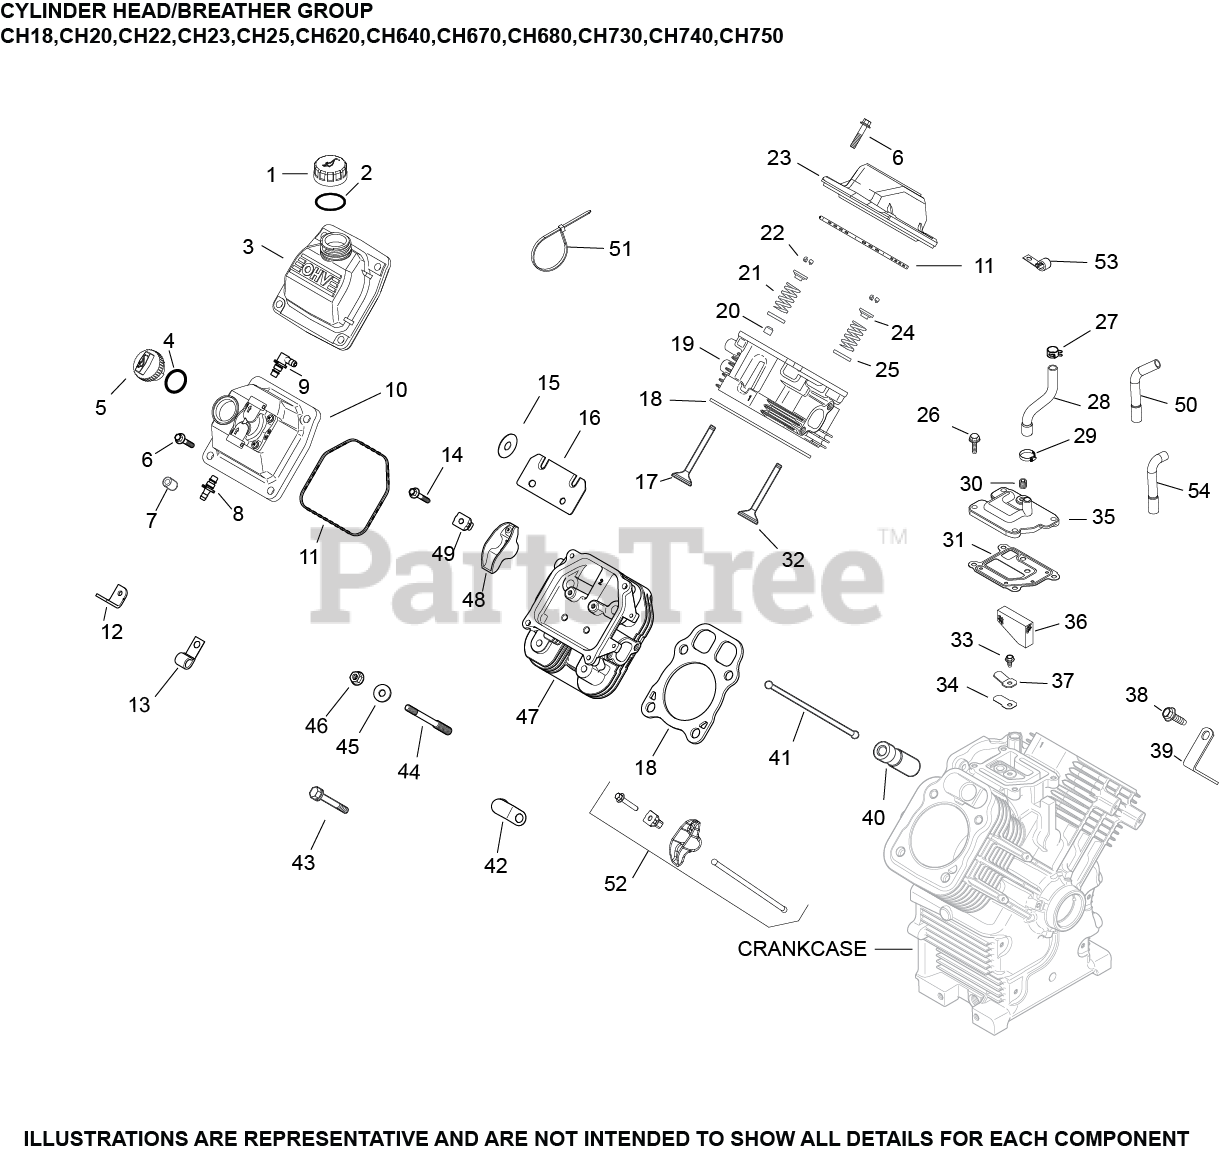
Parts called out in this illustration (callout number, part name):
1	KIT, OIL FILL CAP (BLACK)
2	O-RING, DIPSTICK
3	KIT, VALVE COVER-OIL FILL
6	SCREW, FLG M6X1.0X30
11	O-RING (YELLOW), VALVE COVER
14	SCREW, FLG M6X1.0X34
17	VALVE, EXHAUST (STD) - USE 32 016 01-S
17	VALVE, EXHAUST (.25)
18	KIT, CYL HEAD GASKET (C17-22)
19	HEAD ASSEMBLY, CYLINDER (#1) USE 24 318 173-S
20	SEAL, VALVE BAND
21	SPRING, VALVE
22	KIT, RETAINER
23	KIT, VALVE COVER-PLAIN
24	CAP, VALVE SPRING
25	RETAINER, SPRING
26	SCREW, THREAD FORMING
27	CLAMP SPRING HOSE
28	HOSE, BREATHER
31	GASKET, BREATHER
32	VALVE, INTAKE (STD)
32	VALVE, INTAKE (.25)
33	SCREW, FLG THD FRM M5X.8X10
34	REED, BREATHER
35	KIT, BREATHER ASSEMBLY
36	FILTER, BREATHER
37	RETAINER, REED
38	SCREW, THREAD FORMING
39	STRAP, LIFT
40	LIFTER, VALVE HYDRAULIC - (#2535111S)
41	ROD, PUSH
43	SCREW, FLG M10X1.5X90
47	HEAD ASSEMBLY, CYLINDER (#2) USE 24 318 174-S
48	ARM, ROCKER
49	PIVOT, ROCKER ARM
52	KIT, VALVE TRAIN
24755147-S	KIT, CYLINDER HEAD HARDWARE
